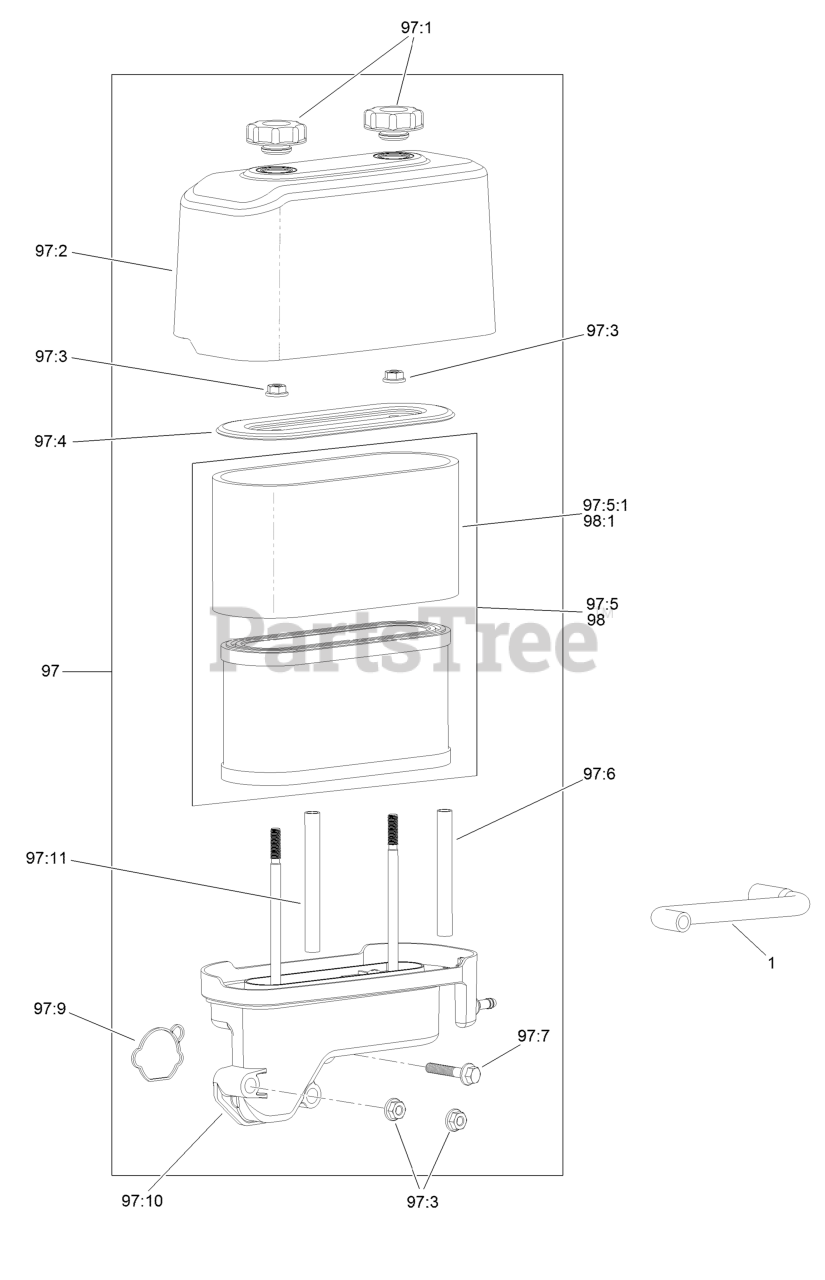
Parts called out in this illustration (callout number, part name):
1	TUBE-BREATHER
97:1	NUT-SPEED
97:2	COVER-FILTER, AIR
97:3	NUT-FLANGE
97:5:1	PREFILTER
97:6	SPACER-FILTER, AIR
97:7	SCREW-HHF
97:9	GASKET-CARBURETOR
97:11	SPACER-FILTER, AIR
98:1	PREFILTER
